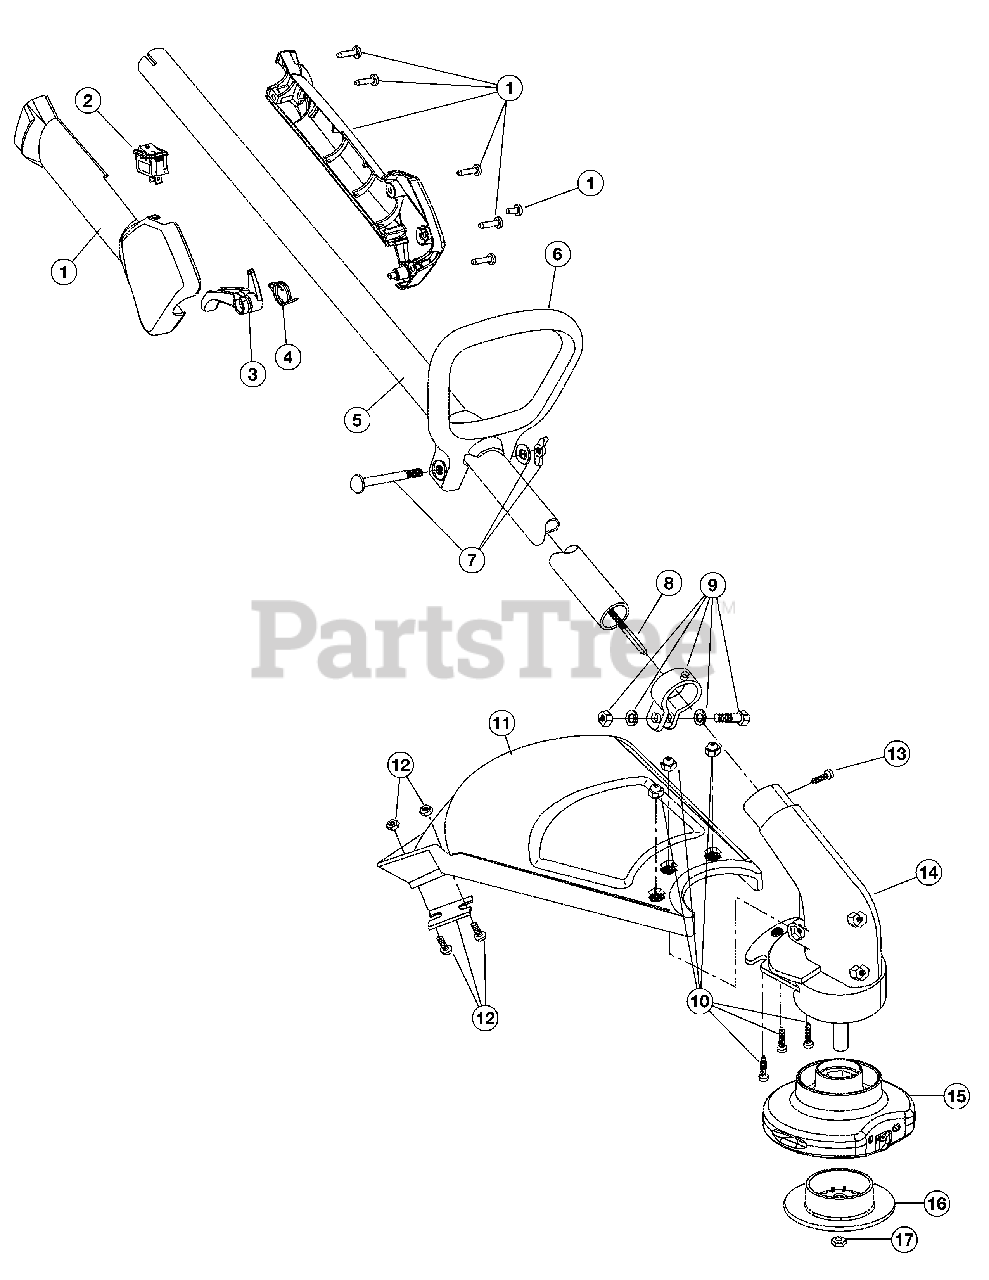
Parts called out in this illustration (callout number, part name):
1	Throttle Housing Assembly (includes 2-4)
3	Throttle Trigger
4	Throttle Trigger Spring
5	Drive Shaft Housing Assembly (includes 8)
6	D-Handle (includes 7)
7	D-Handle Hardware Assembly
8	Flexible Drive Shaft
9	Lower Clamp Assembly (includes 13)
10	Guard Mounting Screw Assembly
11	Guard Assembly (includes 12)
12	Blade Assembly
13	Anti-Rotation Screw
14	Gearbox Assembly
15	Fixed HD Line Assembly (includes 16 & 17)
16	Glide Cap
17	Locknut
